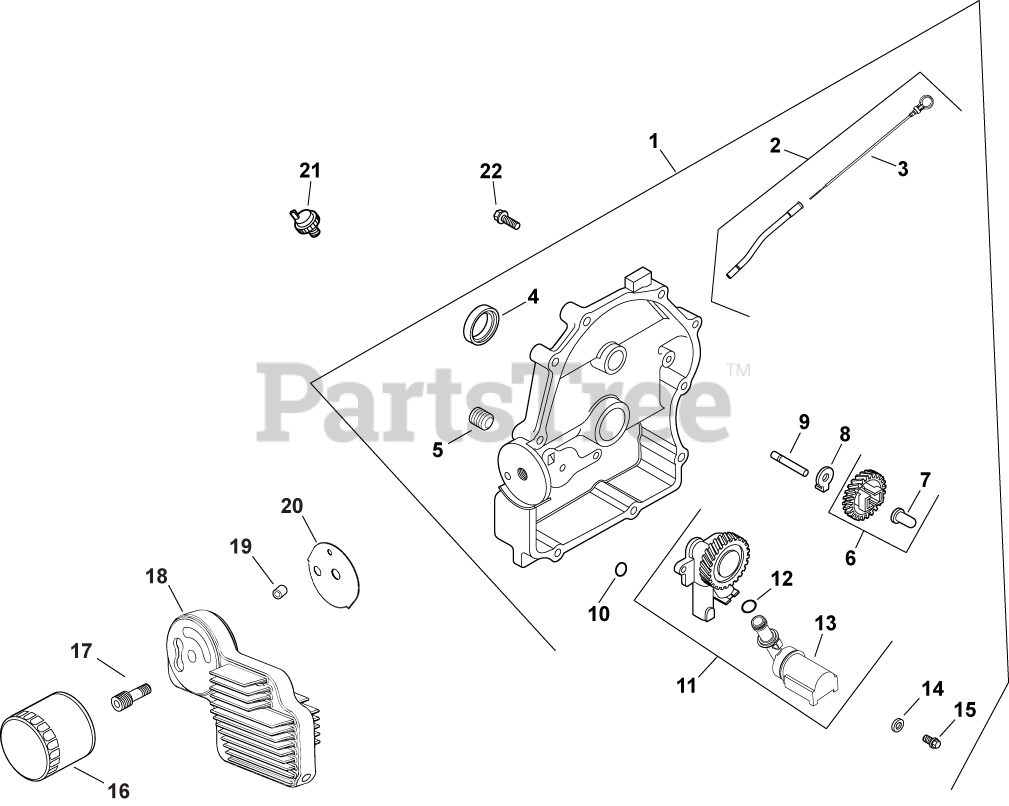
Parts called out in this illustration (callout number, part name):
1	PLATE, CLOSURE & BEARING USE 24 009 227-S
2	KIT, DIPSTICK/DIPSTICK TUBES
4	SEAL, OIL
5	PLUG, CTSK PIPE 1/8"
6	KIT, GOVERNOR GEAR W/PIN
7	PIN, GOVERNOR REGULATING
8	TAB, LOCKING
9	SHAFT, GOVERNOR GEAR
11	PUMP ASSEMBLY, OIL-USE 24 393 53-S
12	O-RING, OIL PICK-UP
13	PICK-UP, OIL
14	SCREW,FLG THD FRM M6X1.0X25-(#25086395S)
15	WASHER, FLAT 6 MM
16	OIL FILTER
17	NIPPLE, OIL FILTER
18	COOLER, OIL ASSEMBLY
19	PIN, LOCATING
20	GASKET, OIL FILTER ADAPTER USE 24 041 88-S
21	SENSOR, OIL PSI
22	SCREW, FLG M8X1.25X45
